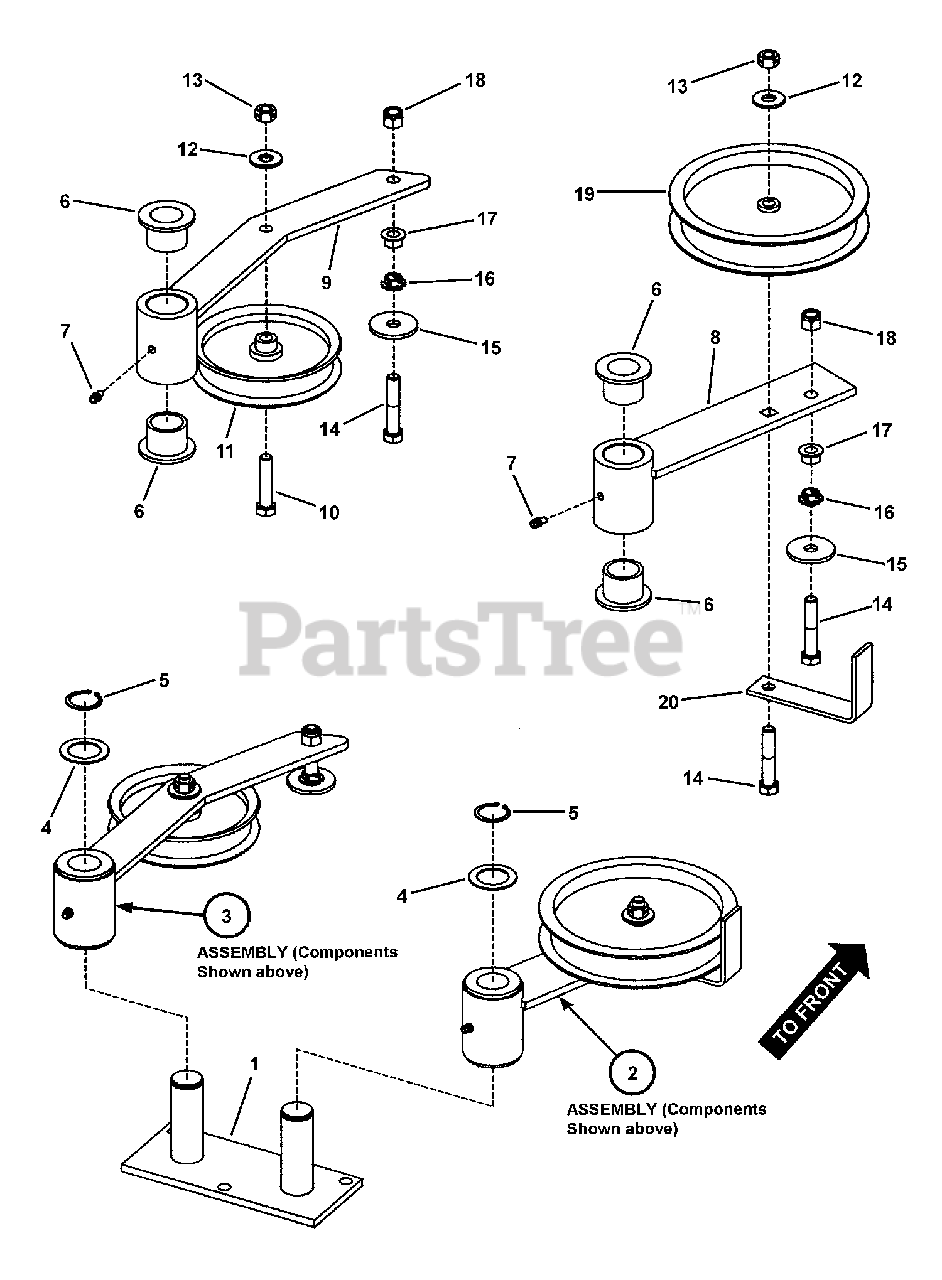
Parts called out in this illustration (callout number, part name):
1	WELDMENT, Idler Pivot Plate
2	ASSEMBLY, Primary Idler
3	ASSEMBLY, Secondary Idler
4	BUSHING, 1" Machine
5	RING, 1" External Retaining
6	BUSHING, Caster
7	LUBE FITTING, 3/16"
8	WELDMENT, Deck Idler Arm
9	WELDMENT, Secondary Idler Bracket
10	SCREW, 3/8-16 x 1-3/4" Hex Head Cap, GR 5
11	PULLEY, Idler
12	WASHER, 3/8" USS
13	NUT, 3/8-16 Hex Center Lock
14	BOLT, 3/8-16 X 2, GD5, CZ
15	WASHER, .406 x 1.50 x .120 Flat
16	BUSHING, 3/8" Plastic
17	NUT, 3/8-16 HEX SERRATED FLANGE
18	NUT, 3/8-16 HEX NYLON LOCK
19	PULLEY, Flat Idler, 5.5 O.D.
20	RETAINER- Belt- Idler
